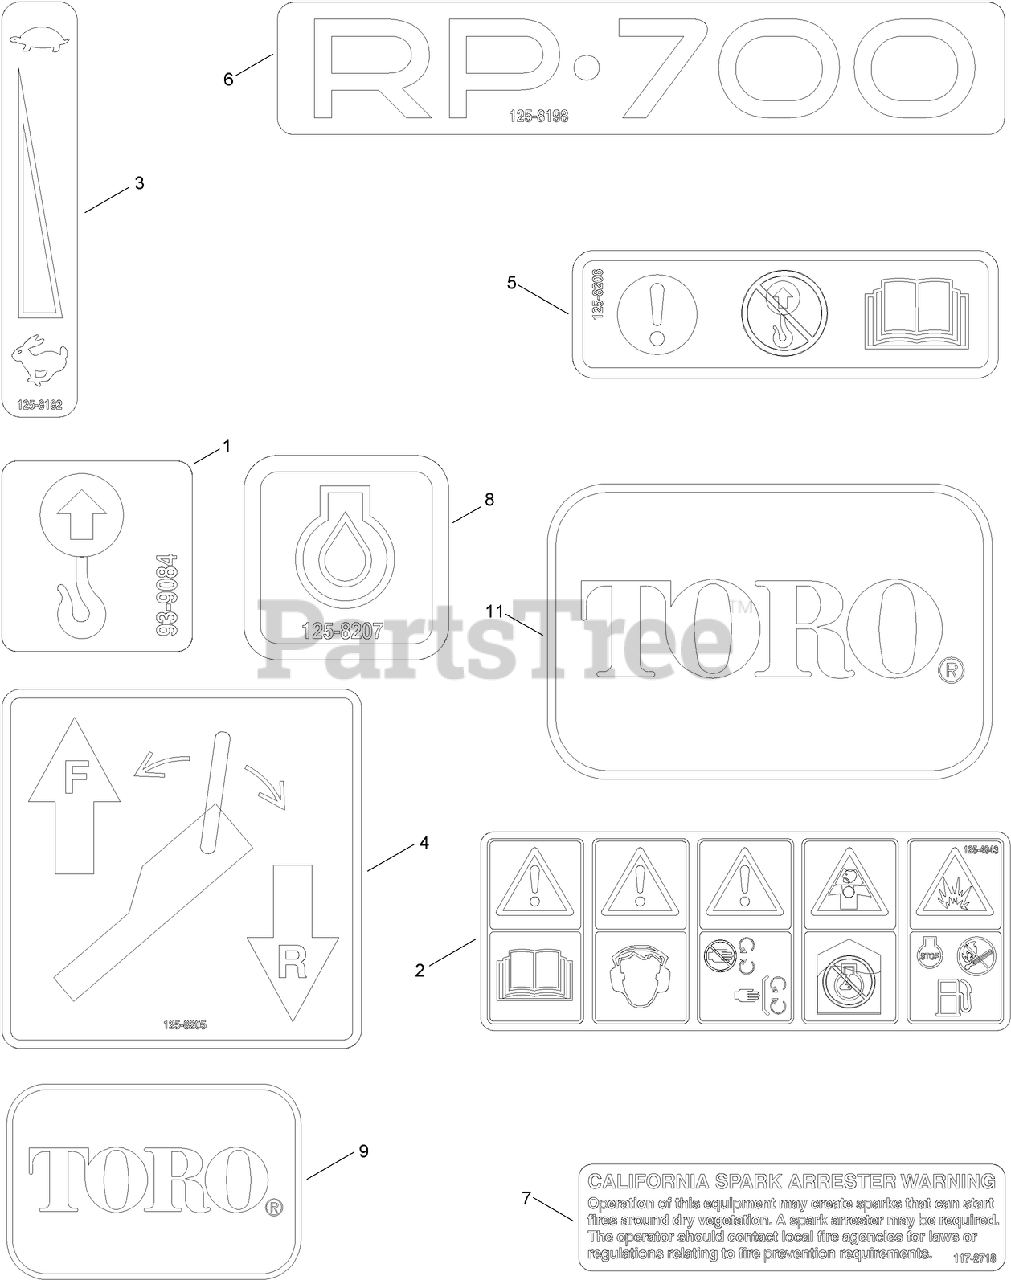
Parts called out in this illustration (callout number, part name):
1	DECAL-POINT, LIFT
2	DECAL-WARNING, PLATE
3	DECAL-THROTTLE
4	DECAL-OPERATION
5	DECAL-CAUTION
6	DECAL (RP-700)
7	DECAL-ARRESTER, SPARK
8	DECAL-OIL, ENGINE
9	DECAL
